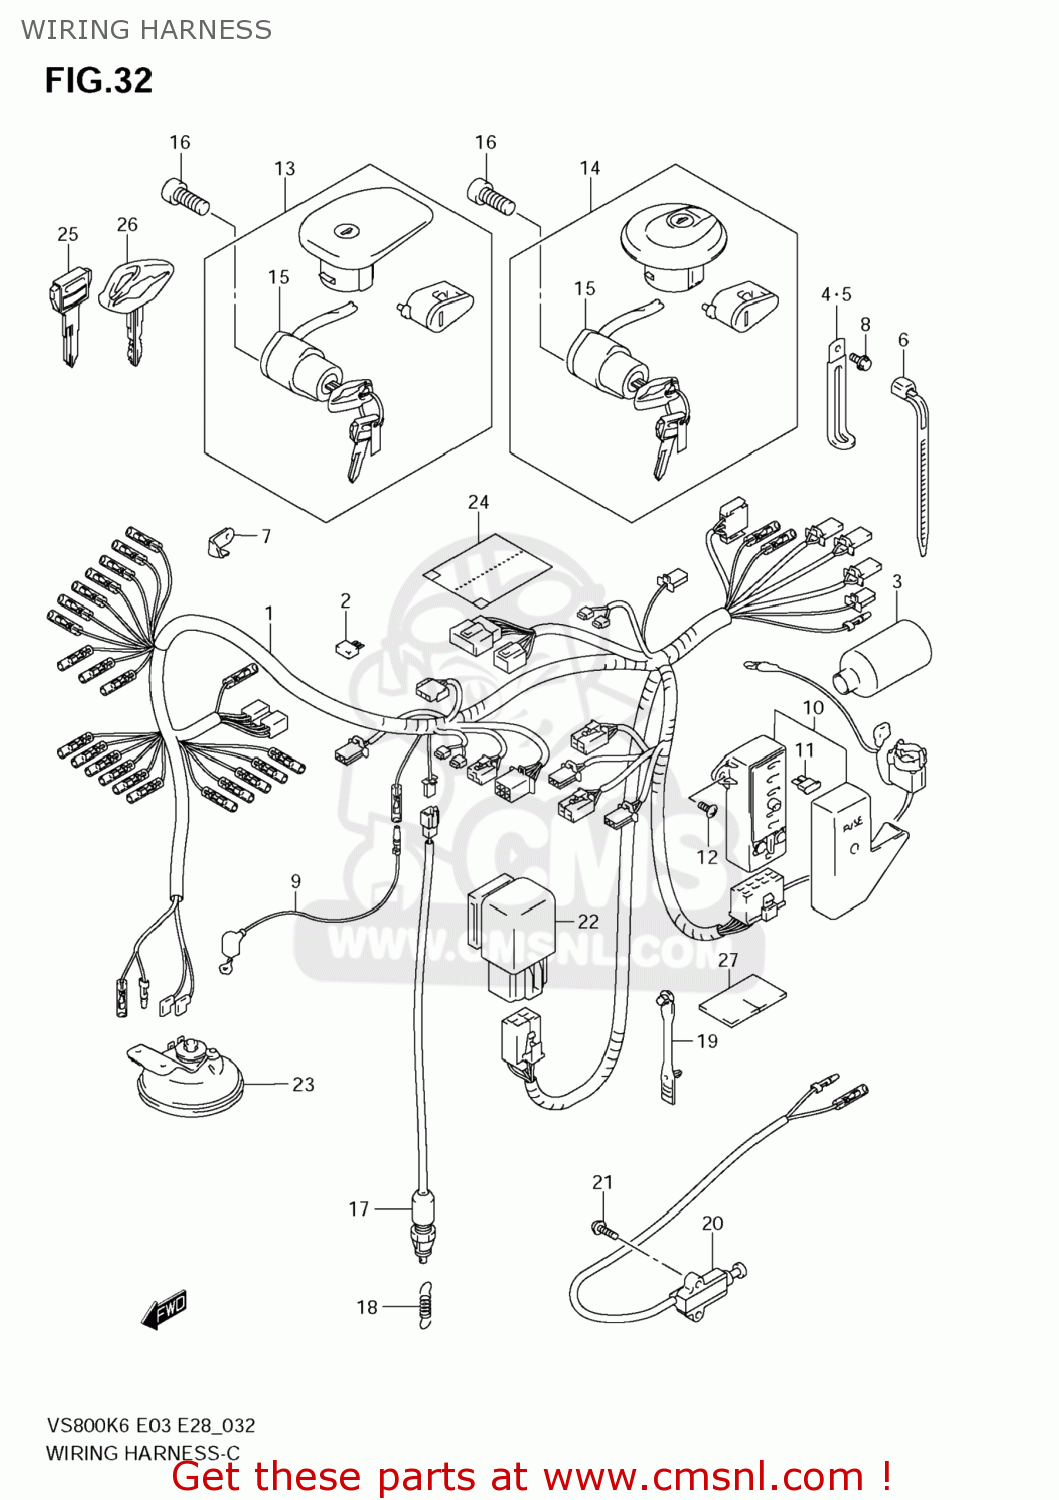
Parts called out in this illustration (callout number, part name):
1	HARNESS,WIRING
2	DIODE(STANLEY DE8804)
3	BOOT,WIRING HARNESS
4	CLAMP(L:80)
5	CLAMP(L:45)
6	CLAMP(L:125)
7	PLATE,COUPLER HOLDER
8	BOLT
9	WIRE,WATER TEMP GAUGE LEAD
10	BOX ASSY,FUSE
11	FUSE(10A)
12	SCREW
13	LOCK SET
14	LOCK SET
15	SWITCH ASSY,IGNITION
16	BOLT
17	SWITCH ASSY,STOP LAMP
18	SPRING
19	CLAMP,L:88
20	SWITCH ASSY,SIDE STAND
21	SCREW
22	RELAY ASSY
23	HORN ASSY
24	COVER,WIRING HARNESS
25	KEY,BLANK(TYPE:C)
26	KEY,BLANK(TYPE:C)
27	COVER,HARNESS
